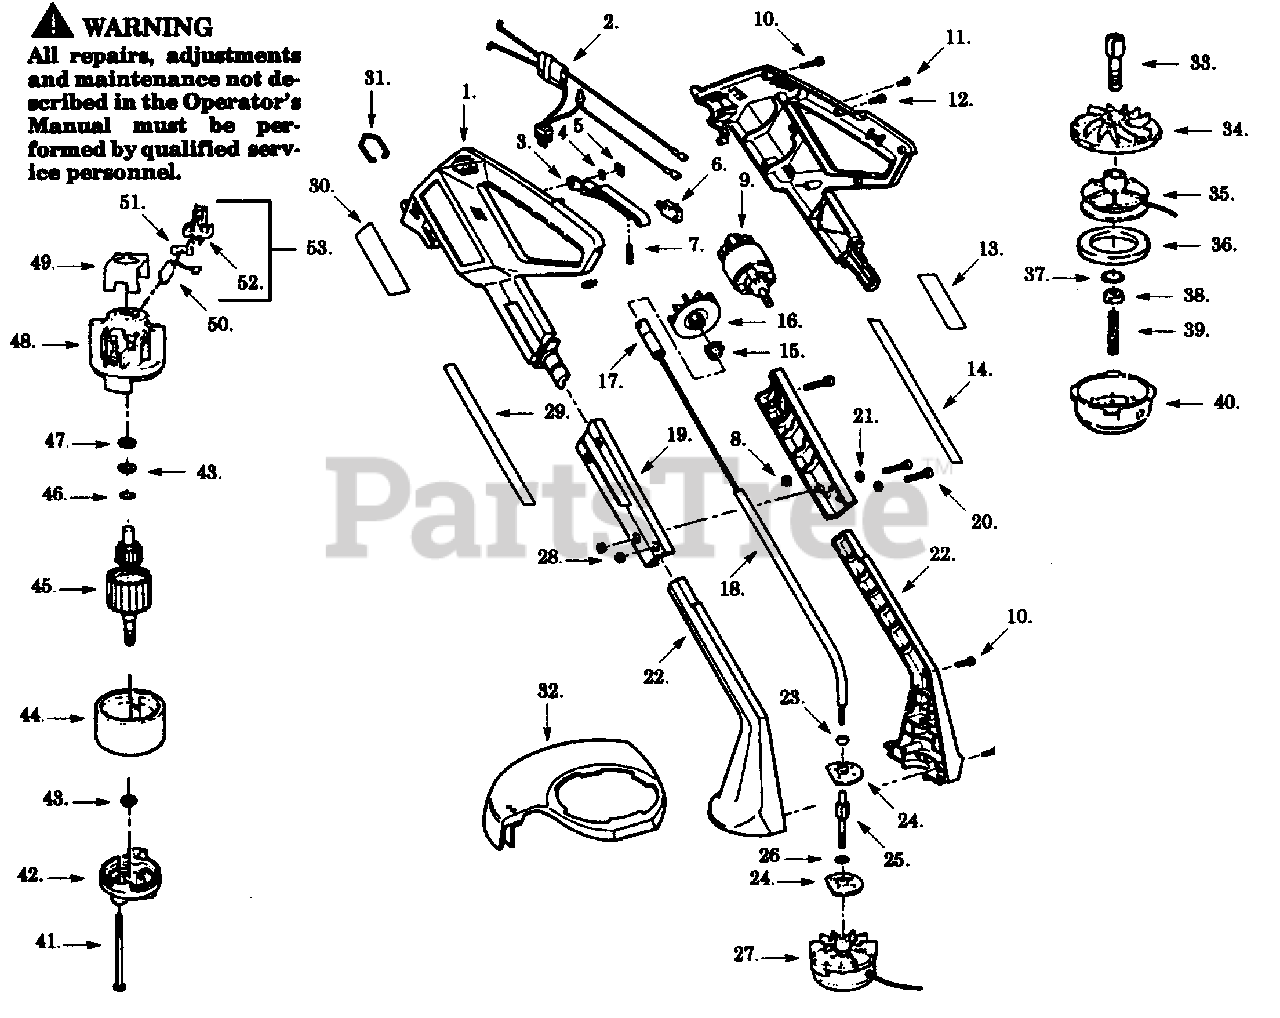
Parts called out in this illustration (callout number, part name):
1	Motor Hsg. Set
5	Push Nut
7	Trigger Spring
8	Square Nut
9	Motor Ass'y.
13	Warning Label (Not a serviceable part)
14	Logo Label (L) (Model 1000)
14	Logo Label (L) (Not a serviceable part)
15	Fan Clamp
17	Flex Shaft Ass'y.
18	Sleeve Tubing
19	Housing Clamp
22	Spindle Housing
24	Bearing Holder Disk
25	Shaft Adapter
27	Head Ass'y. (Model 1000)
27	Head Ass'y. (Model 1200)
29	Logo Label (R) (Model 1000)
29	Logo Label (R) (Model 1200) (Not a serviceable part)
30	Nameplate Label (Model 1000)
30	Nameplate Label (Model 1200)
32	Guard Ass'y. (Model 1000)
32	Guard Ass'y. (Model 1200)
33	Shaft Adapter
34	Rear Plate
35	Spool & Line (Model 1000)
35	Spool & Line (Model 1200)
36	Foam Pad
38	Adapter Nut
40	Hub Ass'y.
42	Endbell Ass'y. (Drive)
44	Field Ass'y.
45	Armature Ass'y.
46	Retaining Ring
48	Endbell Ass'y. (Brush)
49	Insulator
51	Brush Spring
52	Brush Holder
53	Brush Kit (Incl. 50,51,52)
